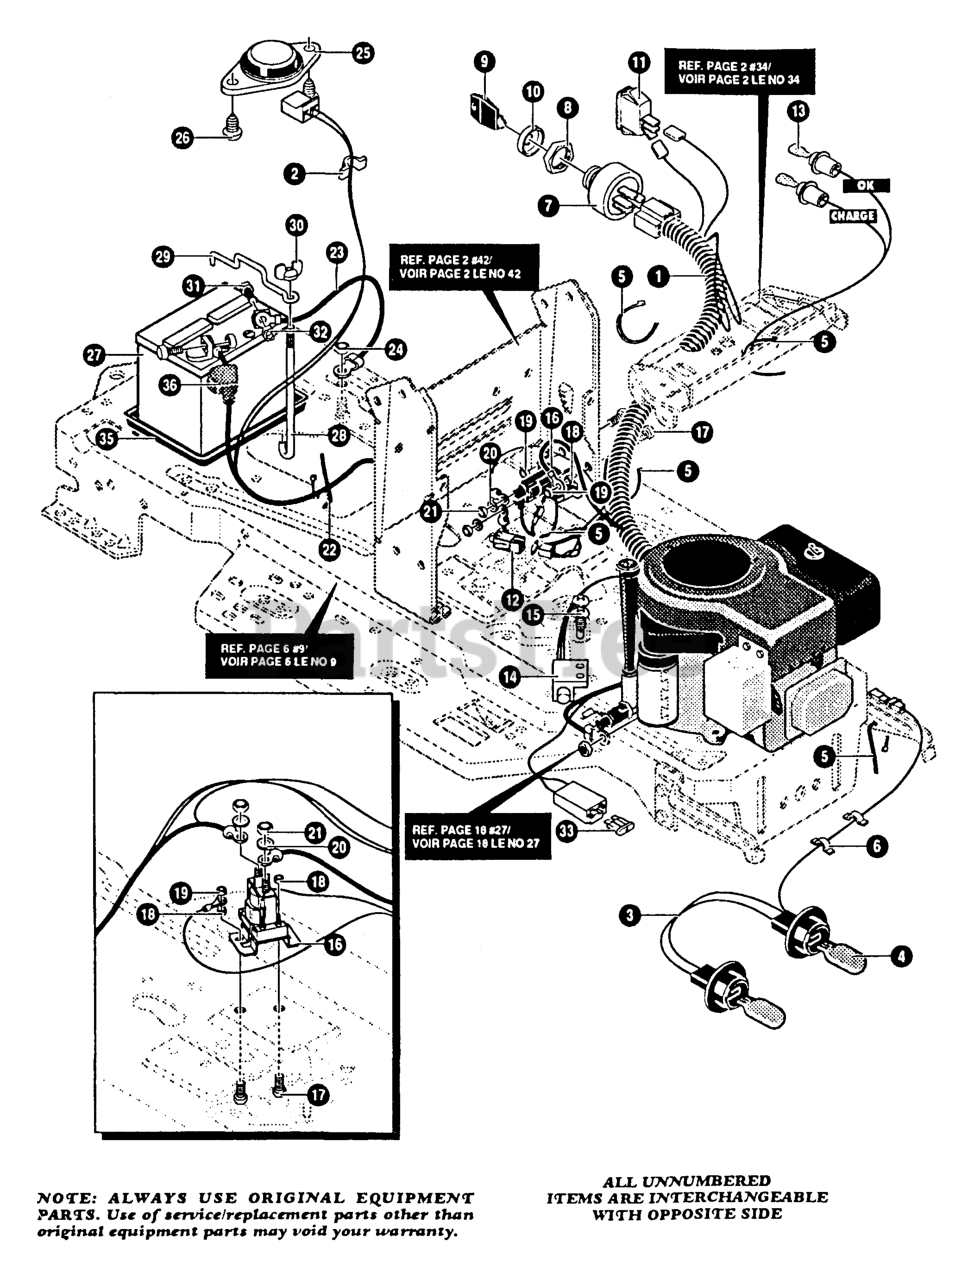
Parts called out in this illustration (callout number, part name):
1	HARNESS, WIRE
2	PRESS CLIP
3	ASSY, LIGHT WIRE
4	BULB, HEADLAMP
5	TIE, CABLE
6	PRESS CLIP
7	SWITCH-IGNITION
9	KEY, IGNITION
10	BOOT, IGN SWITCH
11	LIGHT SWITCH
13	BULB, INDICATOR
16	SOLENOID
17	SCREW
20	WASHER,
22	TIE, CABLE
23	WIRE, GROUND
25	SWITCH, SEAT
27	BATTERY
28	ROD, BATTERY
29	ROD, BATTERY, TOP
33	INCLUDED IN WIRE HARNESS
35	TRAY - BATTERY
36	BOOT, BATTERY
